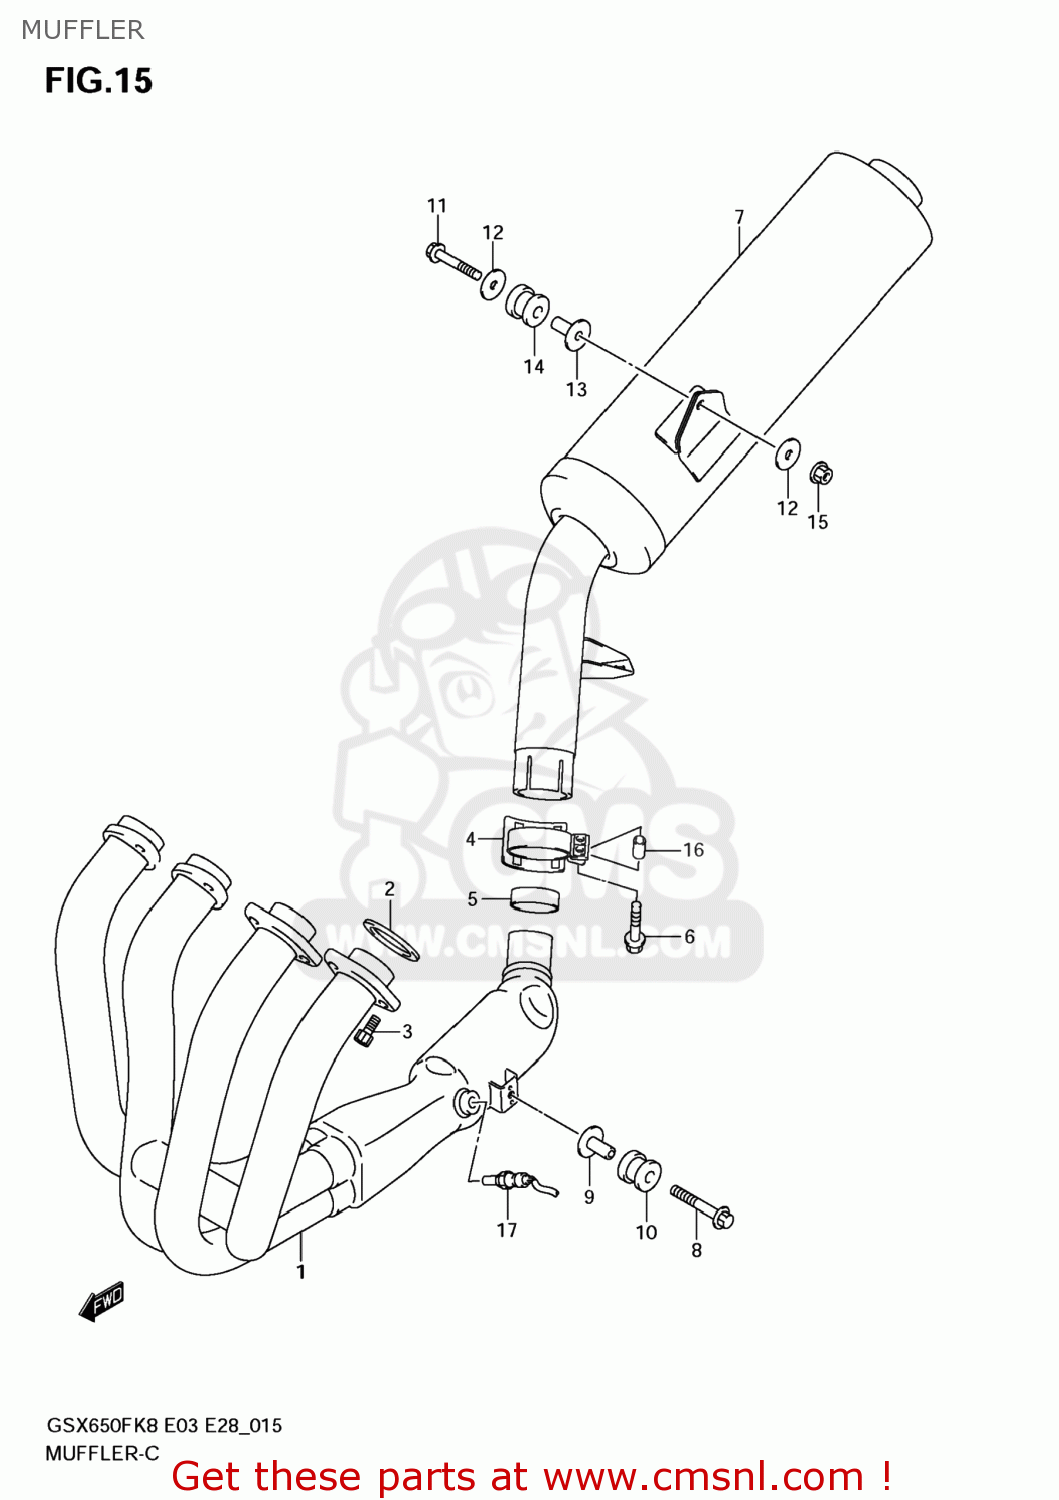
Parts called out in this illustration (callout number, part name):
1	EXHAUST
2	GASKET,EXHAUST (NAS)
3	BOLT(8X25)
4	CLAMP,MUFFLER CONNECTOR
5	CONNECTOR,MUFFLER
6	BOLT(8X40)
7	BODY,MUFFLER
8	BOLT
9	SPACER(8.6X12X24.2)
10	CUSHION
11	BOLT(8X45)
12	WASHER(8.6X36X2)
13	SPACER(8.6X12X25)
14	CUSHION
15	NUT
16	SPACER,CLAMP
17	SENSOR,OXYGEN
